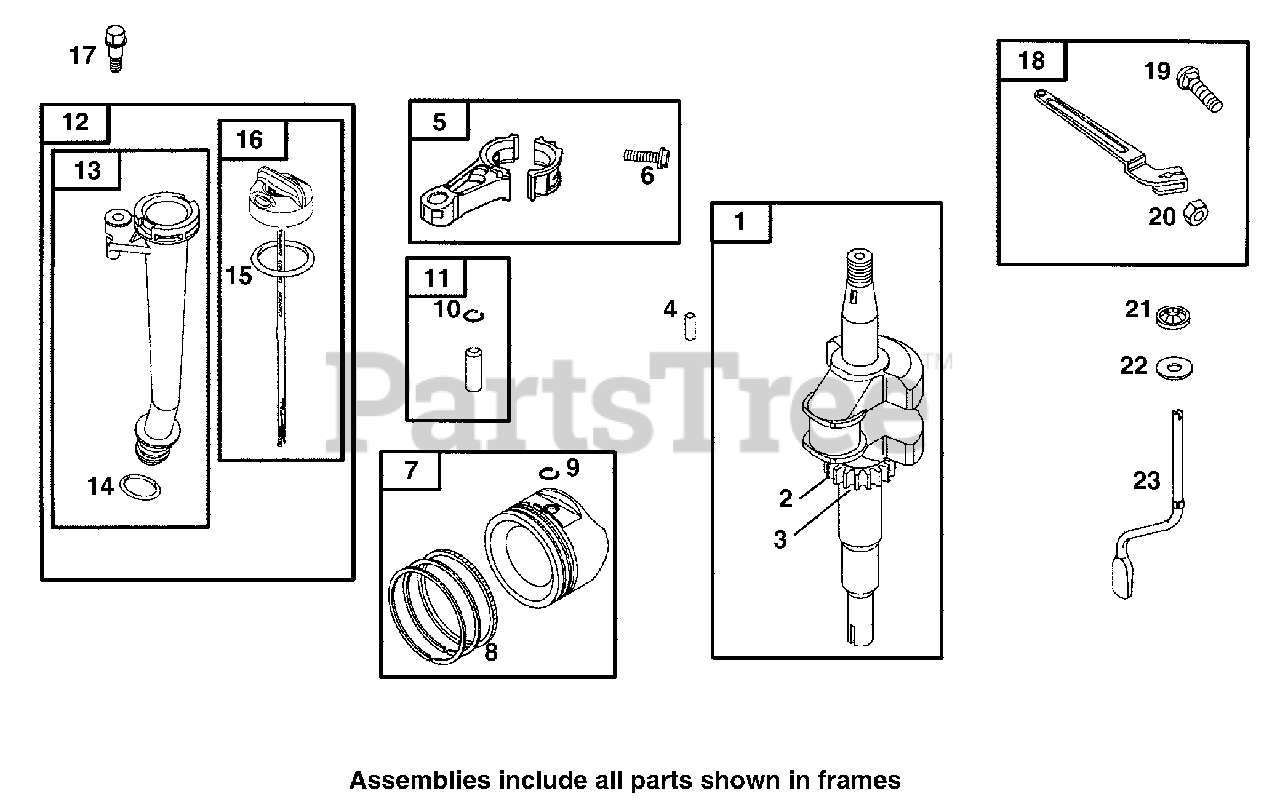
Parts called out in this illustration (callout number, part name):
1	Crankshaft
2	Timing Gear
3	Timing Key
4	Flywheel Key
5	Connecting Rod
6	Connecting Rod Screw
7	Piston Assembly (Standard)
8	Ring Set (Standard)
9	Piston Pin Lock
10	Piston Pin Lock
11	Piston Pin (Standard)
12	Dipstick/Tube Assembly
13	Oil Fill Tube
14	Seal-O-Ring
15	Seal-O-Ring
17	Shoulder Screw
18	Governor Lever
19	Governor Lever Bolt
21	Governor Shaft Retainer
22	Flat Washer
23	Governor Crank
